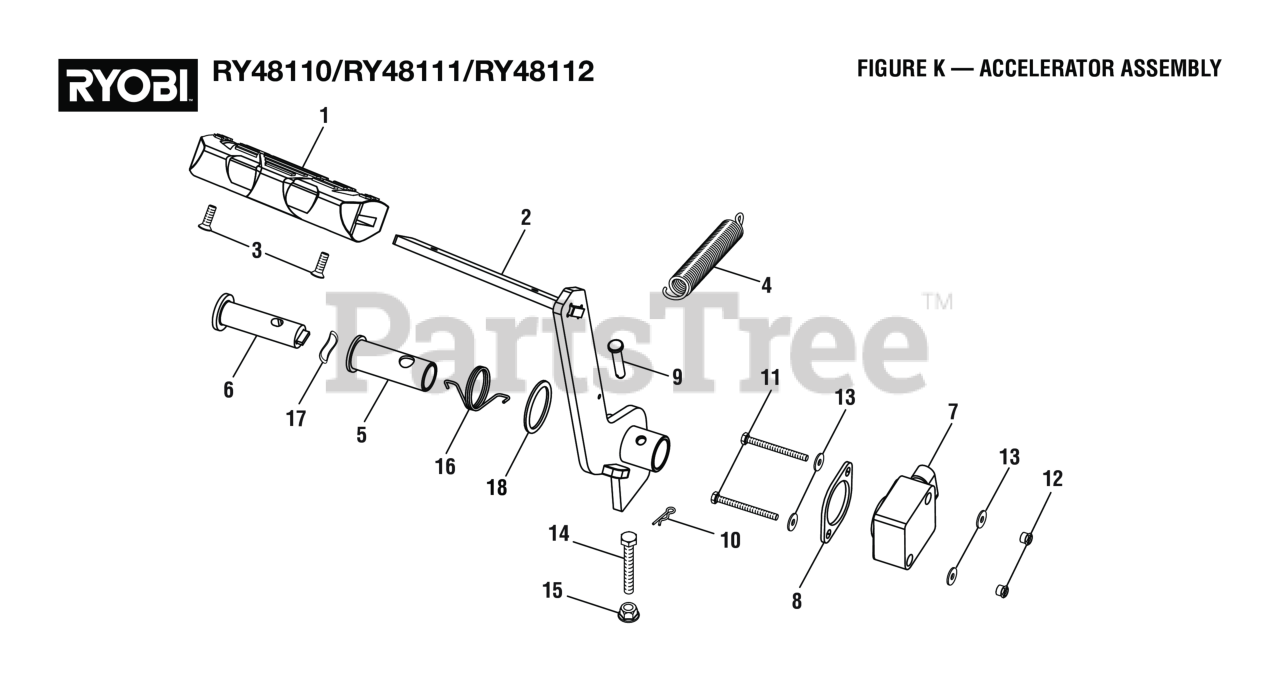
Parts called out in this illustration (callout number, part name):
1	Brake Pedal
2	Acceleration Pedal
3	Screw (M5 x 16 mm, Flat Hd.)
4	Pedal Spring
5	Accelerator Axle Bushing
6	Accelerator Axle
7	Speed Control Switch
8	Control Switch Mounting Bracket
9	Clevis Pin (6 x 30 mm)
10	Cotter Pin (6 mm)
11	Bolt (M4 x 45 mm, Hex Hd.)
12	Nut (M4 x 0.7, Lock)
13	Washer (OD12 x ID4.3 x 1t)
14	Bolt (M6 x 45 mm, Hex Hd.)
15	Flange Nut (M6)
16	Torsion Spring
17	Spring Washer (OD20.5 x ID17 x 0.3t)
18	Adjusting Shim Kit
